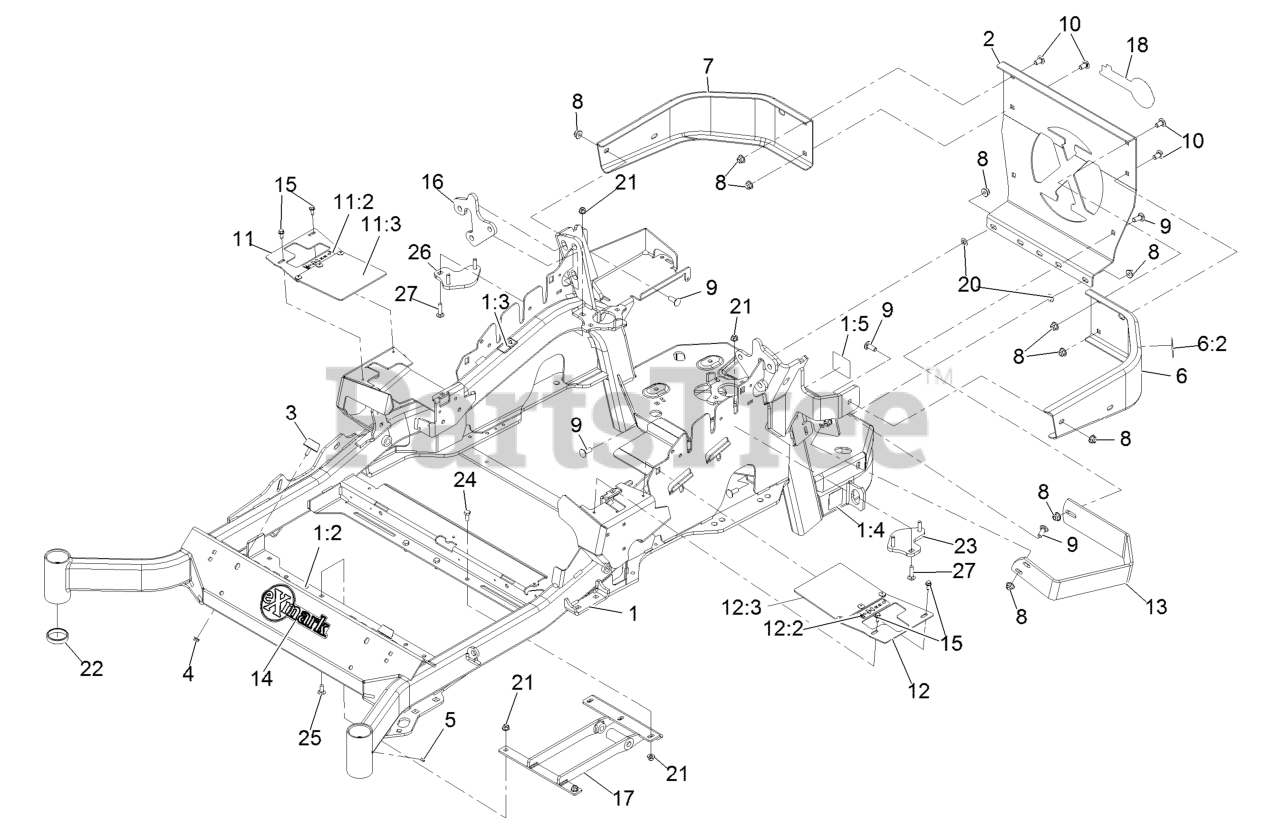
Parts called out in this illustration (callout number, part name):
1	Mainframe ASM
1:2	Decal-Danger
1:3	Decal-Warning
1:4	Decal-Hazard, Pinched Finger
1:5	Decal-Spark Arrester
2	Plate,Rear Guard
4	Nut-Nyloc 1/4-20 Flg
6	LH Bumper ASM
6:2	Decal-Warning
7	Bumper-RH
8	Nut-Nyloc 3/8-16 Flg
9	Bolt-Carriage 3/8-16 X 1
10	Bolt-Carriage 3/8-16 X 3/4
11	RH Motion Control Cover ASM
11:2	Decal-Control, Motion
11:3	Flap-Rubber
12	LH Motion Control Cover ASM
12:2	Decal-Control, Motion
12:3	Flap-Rubber
13	Guard-Muffler
14	Decal-Exmark
15	Screw-HWH 1/4-20 X .62
16	Plate-Mount, Shock
17	Mount-Lower
18	Decal-Exmark Logo
20	Nut-Push 3/8-16
21	Nut-Nyloc 5/16-18 Flg
22	Cup-Bearing Tapered Roller
23	LH Plate ASM (W/Studs)
24	Screw-HH 5/16-18 X 3/4
25	Bolt-Carriage 5/16-18 X 3/4 Short Neck
26	RH Plate ASM (W/Studs)
27	Bolt-Carriage 5/16-18 X 1 1/4
